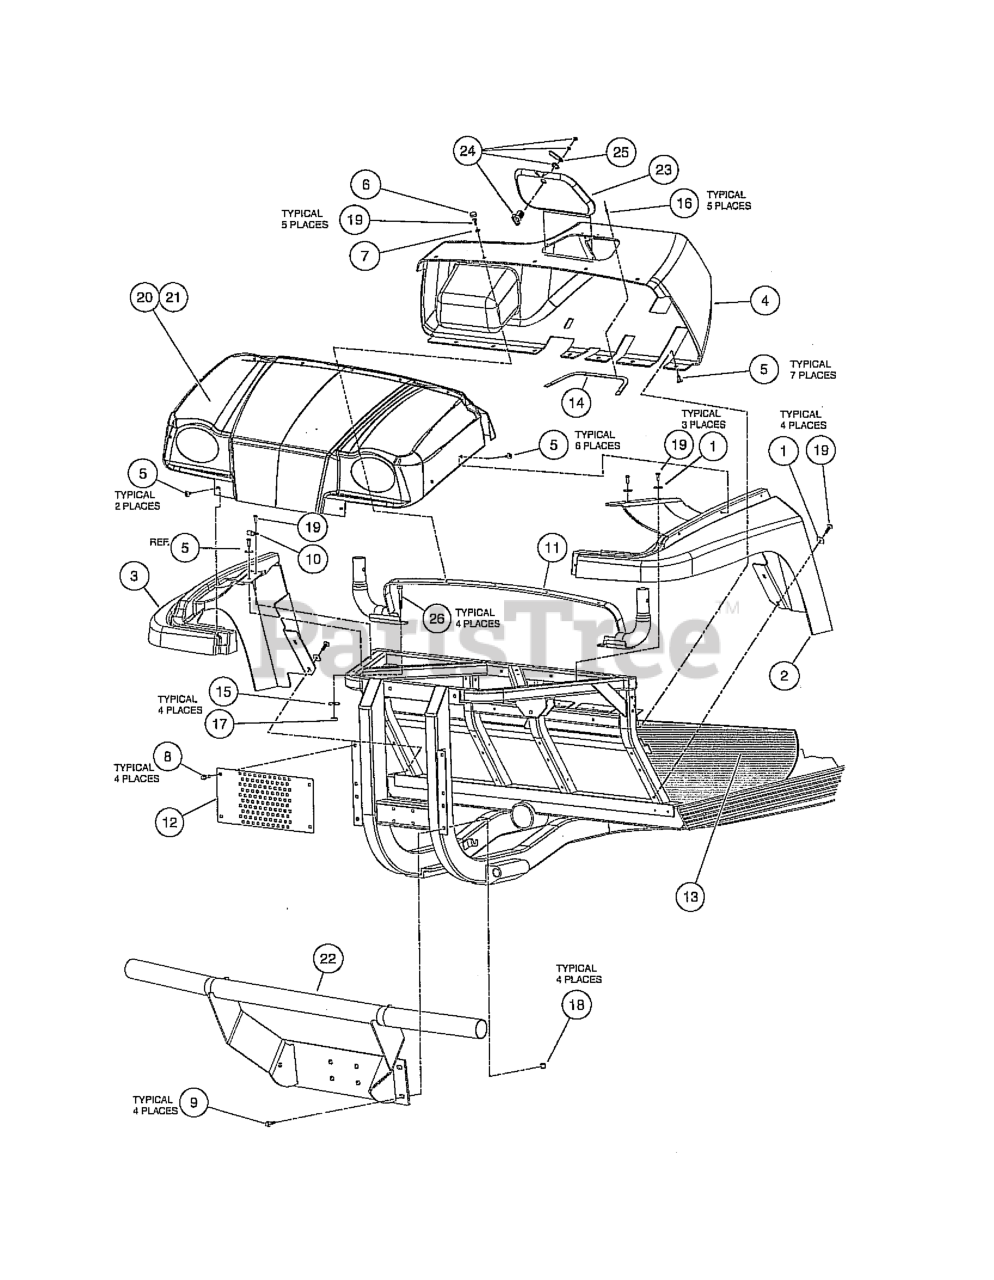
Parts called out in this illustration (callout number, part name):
2	FENDER, LEFT FRONT B
3	FENDER - RIGHT FRONT B
4	DASH BOARD WITH ACCESS HOLE
5	SCREW, TUFLOK PANEL, 1/4
8	SCREW, M8 X 1.25 X 30 TRI, BLK
9	BOLT - FLANGED HD, M8 X 30.0
10	P-CLAMP, INSULATED .312 IN
11	WELDMENT, SUPP, COWL, ROPS
12	GRILL, FLAT
13	MAT, FLOOR AWD
14	SUPPORT, ACCESS PANEL, DASH
15	WASHER HARD, M10
16	RIVET, .125" DIA, .311" PANEL
17	NUT FLG M10 X 1.5 MECH DEF
18	LOCK NUT, FLG M8 X 1.25 NYLON
19	SCREW, 1/4-20X1.0 PN HD TORX
20	Cowl, Camo
21	COWL, OEM, ORANGE
22	Brush Guard
23	PANEL, ACCESS, DASH
24	CAM LOCK BODY
25	LATCH, CAM, ACCESS PANEL
26	BOLT, M10 X 1.50 X 65
